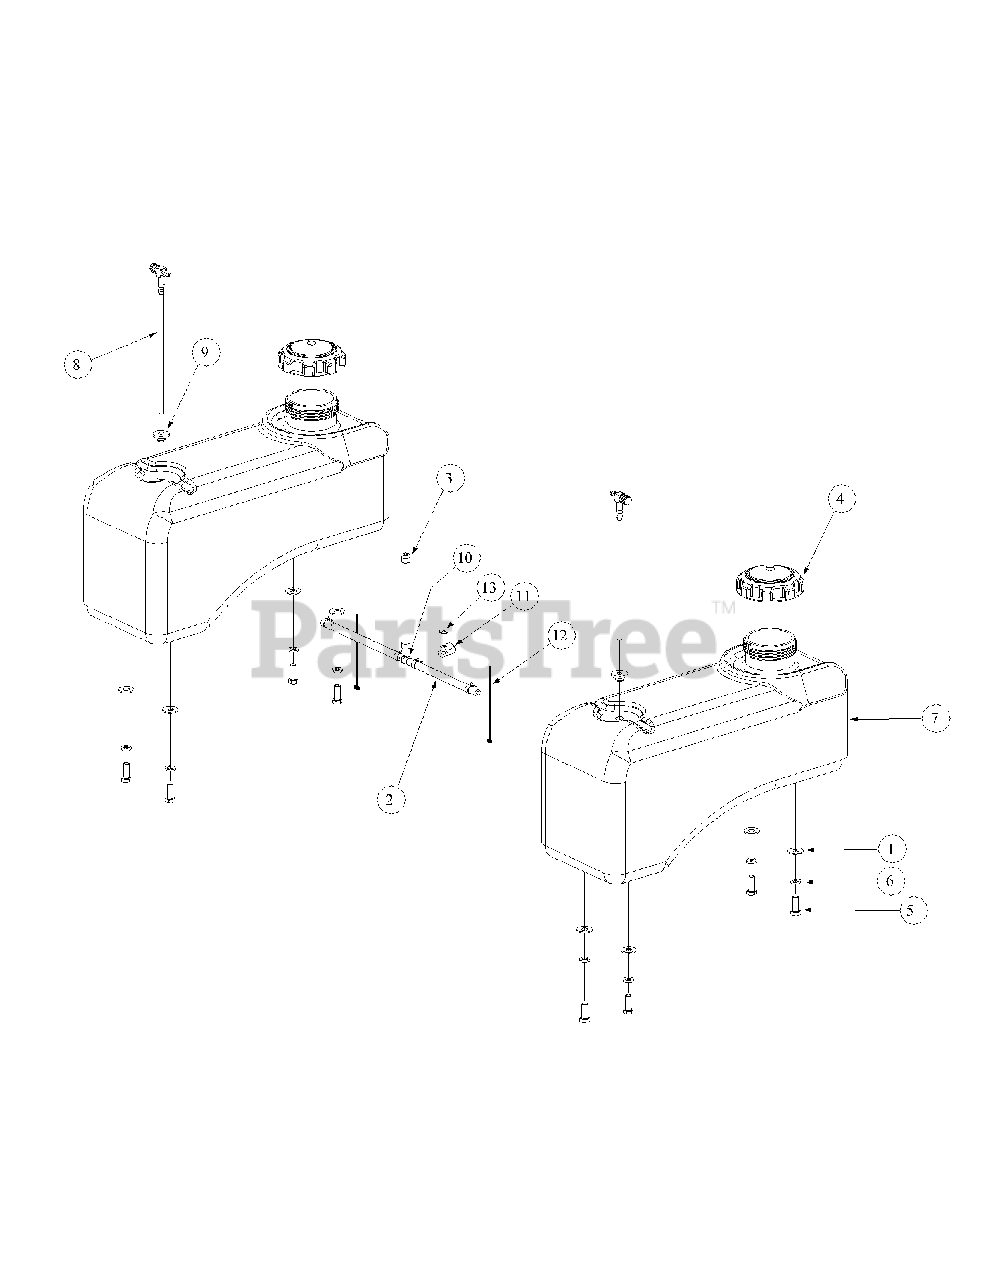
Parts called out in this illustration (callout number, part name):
1	Flat Washer, .406 ID, 1.0 OD, .105
2	Hose, 1/4" Fuel Line 79.5 inches
3	Clamp, Union
4	Fuel Cap, 3.5
5	Hex, Cap Screw, 3/8-16, .88
6	Lock Washer, 3/8
7	Fuel Tank
8	Fuel Fitting
9	Grommet, Fuel Tank
10	Tee Fitting, Fuel
11	Clamp, 1/2 Tubing
12	Cable Tie
13	Flat Washer, 1.4 x .630 x .0515
